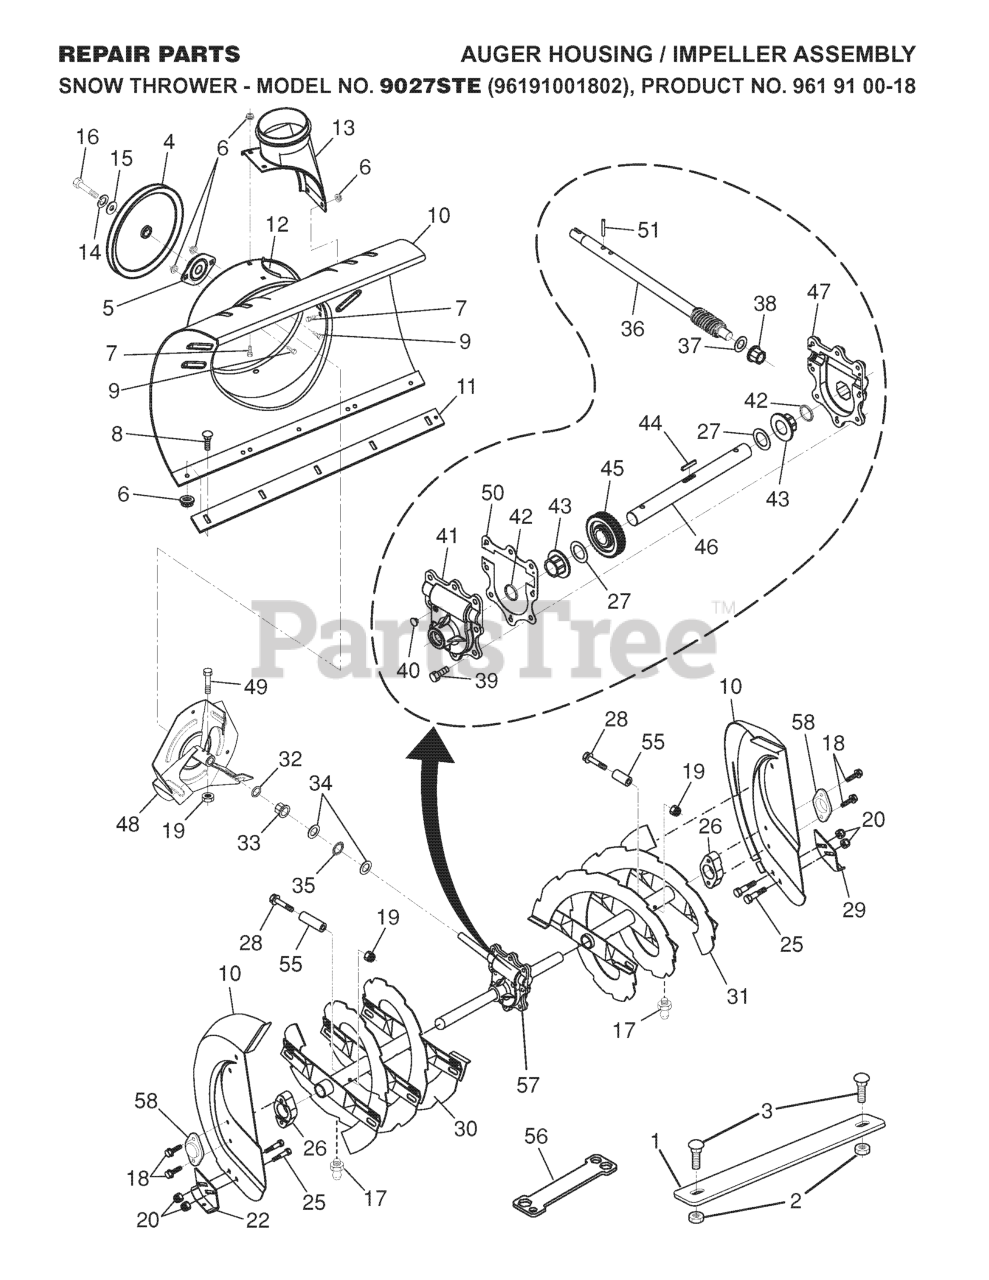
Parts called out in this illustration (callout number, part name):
1	WEIGHT,AUGER HOUSING 27 (2 2MC
2	NUT.LOCK.5/16-18
3	BOLT.CARRIAGE.5/16-18
4	PULLEY, IMPELLER
5	BEARING FLANGE
6	NUT.FLANGE.5/16
7	BOLT.CARRIAGE.5/16-18X
8	BOLT
9	BOLT, HEX HEAD 5/16-18
10	HOUSING, AUGER
11	BAR, SCRAPER
12	BRACKET, CORNER DISCHARGE
13	BASE DISCHARGE CHUTE
14	WASHER, FLAT
15	WASHER.LOCK.HVY.HLCL.SPR.5/16
16	CAPSCREW.HX.HD.5/16-18X1.00.NY
17	GREASE FITTING
18	SCREW, HEX HD 5/16X1
19	LOCKNUT.NYLOC.1/4-20
20	NUT.FLANGE.5/16
22	SKID PLATE RH
25	BOLT
26	BEARING RETAINER, PLASTIC
27	WASHER TRUST 1"
28	BOLT, SHEAR
29	SKID PLATE LH
30	AUGER ASSY-LH
31	AUGER ASSY-RH
33	BUSHING, FLANGE 3/4
34	WASHER, THRUST 3/4
35	BEARING TRUST 3/4 NTA-1220
36	SHAFT, IMPELLER
37	WASHER, THRUST 5/8
38	FLANGE BUSHING-5/8
39	HEX SCREW-5/16 X 3/4
40	CASE PLUG
41	GEARBOX HOUSING-RH
42	OIL SEAL
43	FLANGE BUSHING-1"
44	KEY, SQUARE 1/4 X .875
45	WORM GEAR
46	AUGER SHAFT
47	HOUSING.GEARBOX.LH(SERVICE)
48	IMPELLER ASSY
49	SCREW.HEX.HD1/4-20X
50	GEARBOX GASKET
51	PIN, ROLL 3/16 X 1-1/8
55	SPACER.3943.SLEEVE.250X.47
56	RP WRENCH, SNOWTHROWER
57	GEARBOX.ASSEMBLY.AUGER
58	BEARING.BALL.AUGER.SHAFT
